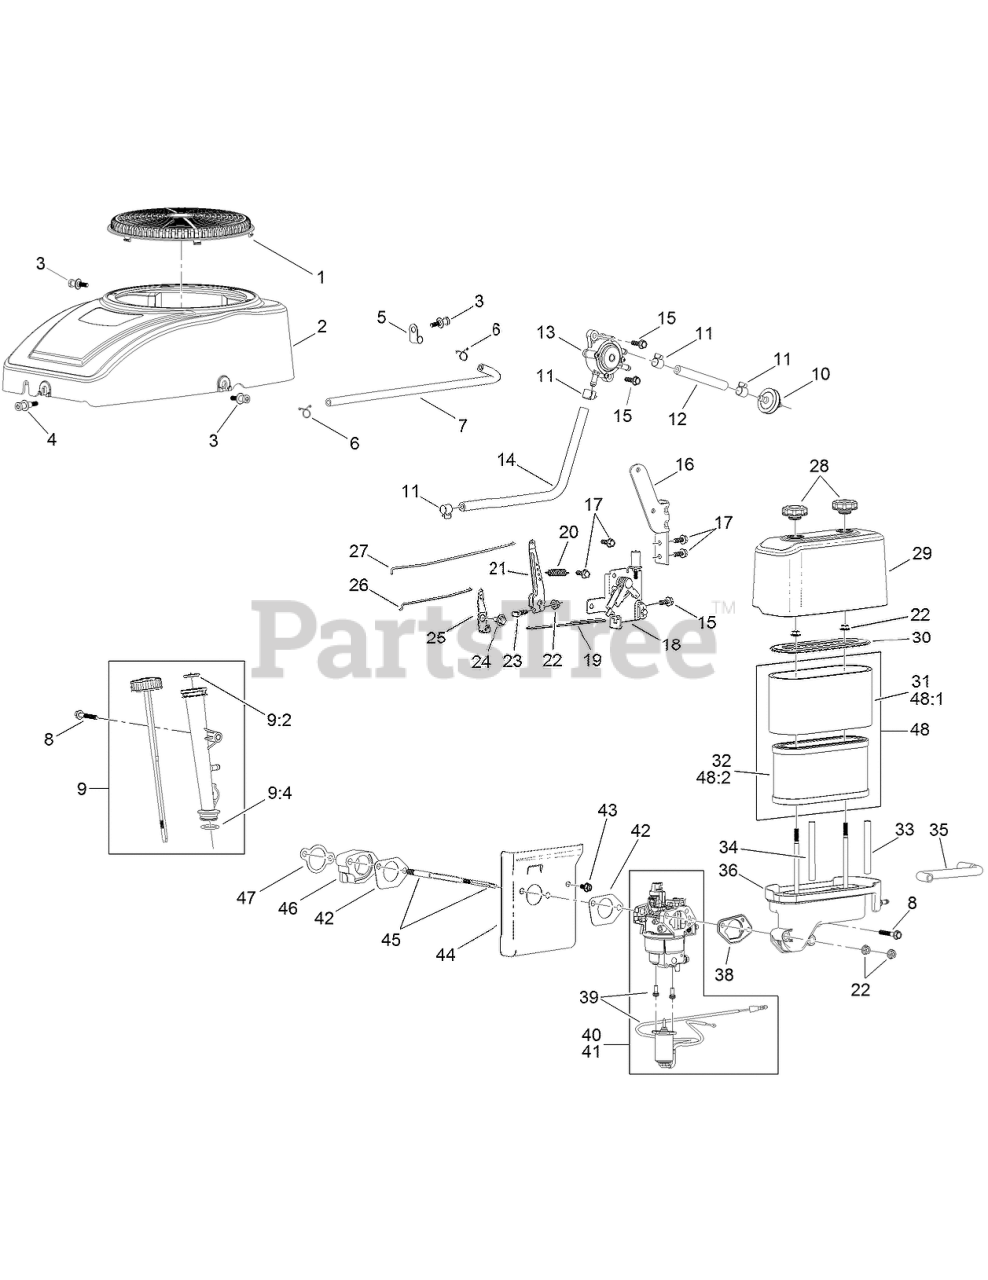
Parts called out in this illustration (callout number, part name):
1	SCREEN-STATIONARY
2	SHROUD-FAN
3	SCREW-SHOULDER, HH
4	SCREW-SHOULDER, HH
5	CLAMP-J
6	CLAMP-HOSE
7	LINE-PULSE
8	SCREW-HHF
9	DIPSTICK AND TUBE KIT
9:2	O-RING
9:4	O-RING
10	FILTER-FUEL
11	CLAMP-FUEL LINE
12	LINE-FUEL
13	PUMP-PULSE, FUEL
14	LINE-FUEL
15	SCREW-HHF
16	BRACKET-PUMP, FUEL
17	SCREW-HHF
18	CONTROL-THROTTLE
19	ROD-THROTTLE
20	SPRING-GOVERNOR
21	ARM-GOVERNOR
22	NUT-FLANGE
23	BOLT-ARM, GOVERNOR
24	SCREW-SHOULDER, HHF
25	BELLCRANK-CHOKE
26	ROD-CHOKE
27	ROD-GOVERNOR
28	NUT-SPEED
29	COVER-FILTER, AIR
30	RETAINER-AIR FILTER
31	PREFILTER
32	FILTER-AIR
33	SPACER-FILTER, AIR
34	SPACER-FILTER, AIR
35	TUBE-BREATHER
36	BASE-FILTER, AIR
38	GASKET-BASE, FILTER
39	SOLENOID KIT
40	CARBURETOR KIT
41	CARBURETOR REPAIR KIT
42	GASKET-CARBURETOR
43	SCREW-HHF
44	SHIELD-HEAT
45	STUD-MOUNT, CARBURETOR
46	INSULATOR-CARBURETOR
47	GASKET-CARBURETOR
48	AIR FILTER KIT
48:1	PREFILTER
48:2	FILTER-AIR
